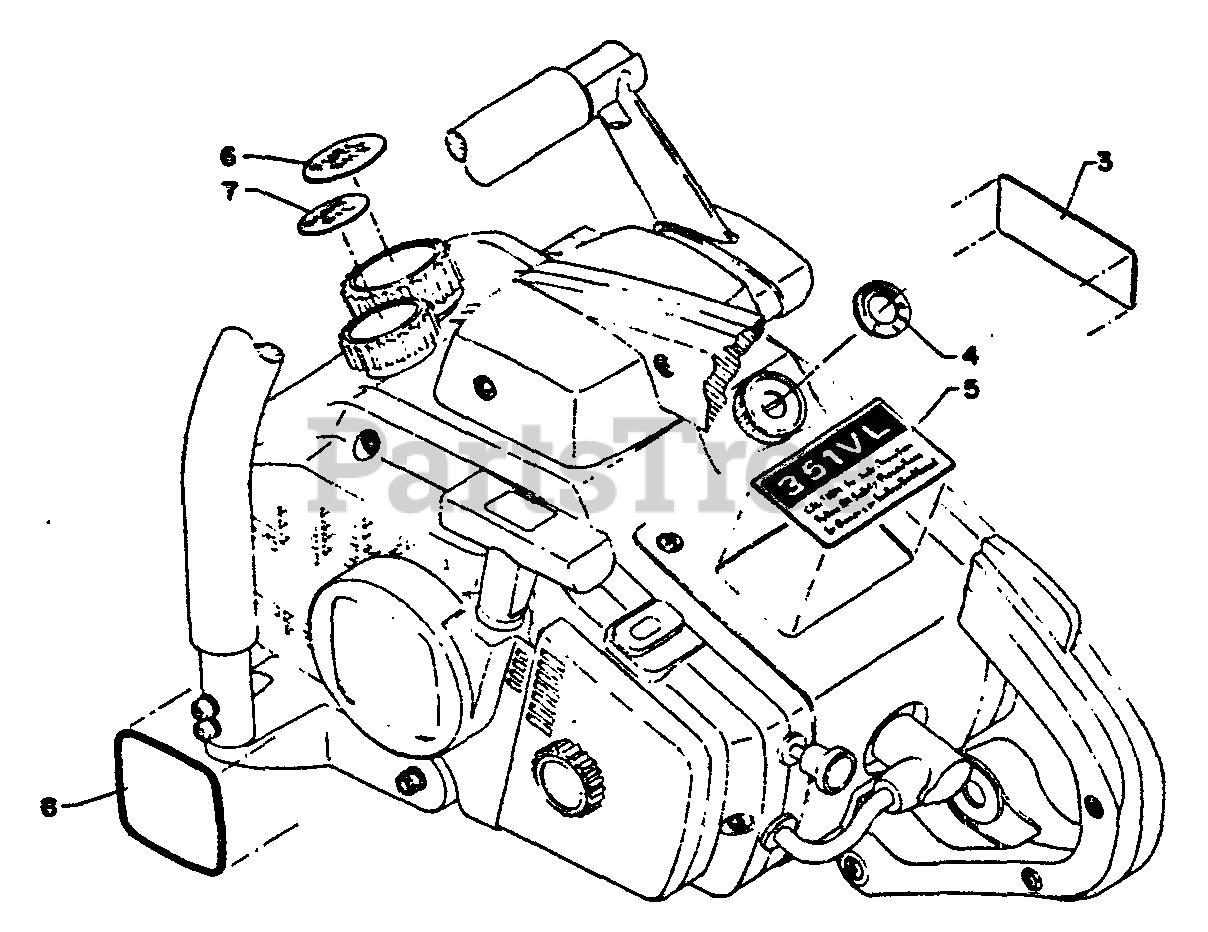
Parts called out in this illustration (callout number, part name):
3	LABEL - ECHO
4	LABEL, CAUTION
5	MODEL PLATE
6	LABEL - FUEL
7	LABEL - OIL
8	LABEL - ECHO
